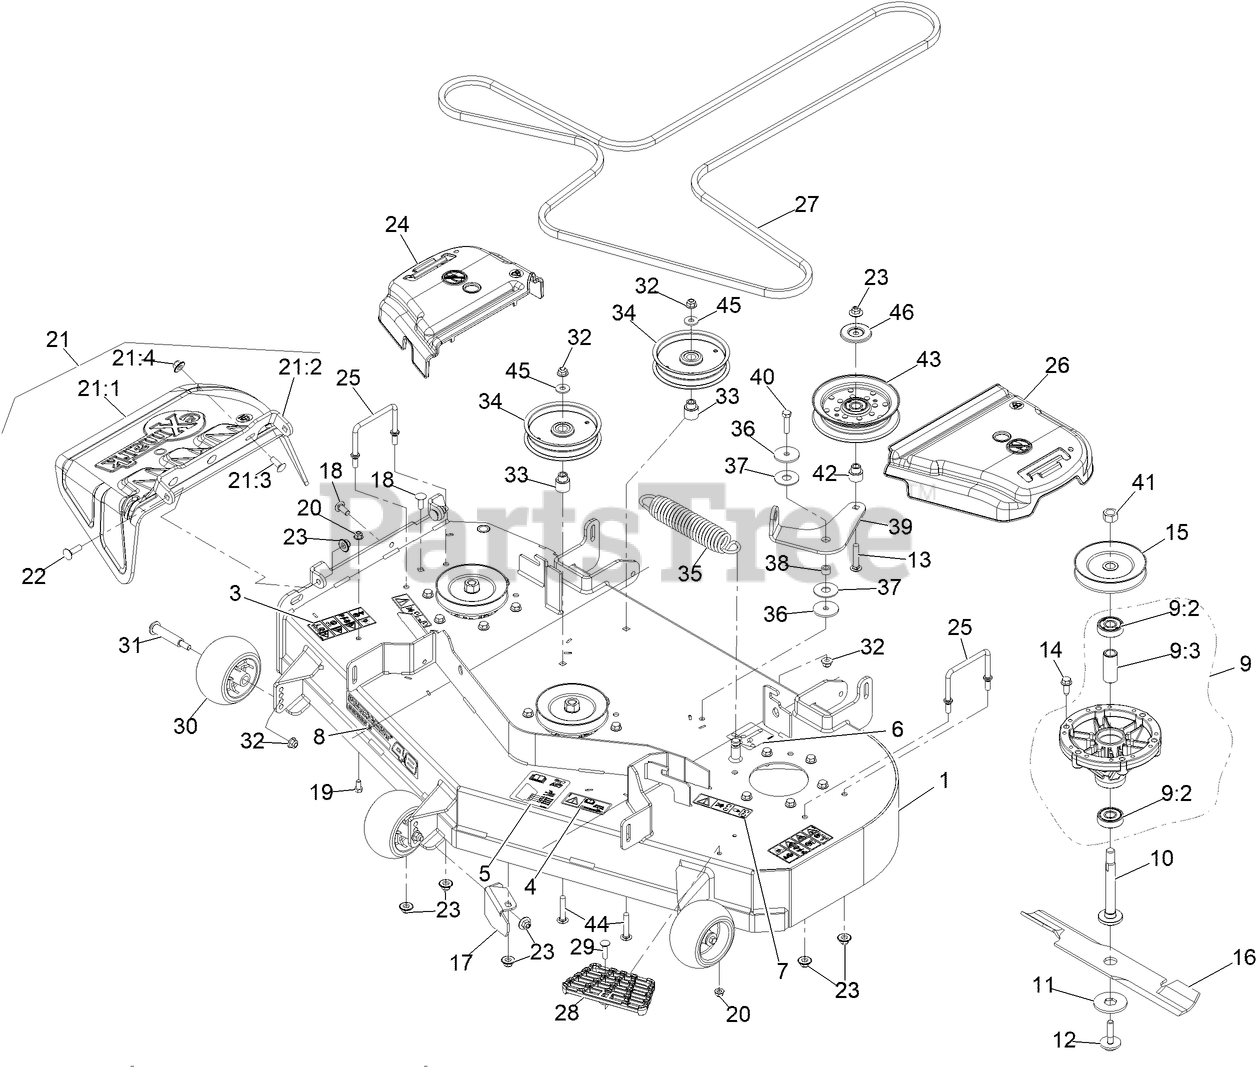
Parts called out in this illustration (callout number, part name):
1	ASM-Deck W/Decals 483
3	DECAL-DANGER, DECK
4	DECAL-TORQUE, BOLT
5	DECAL-ROLLER, ANTI-SCALP
6	DECAL-BELT ROUTING
7	DECAL-COVER, MISSING
8	DECAL-ULTRACUT 48 SERIES 3
9	ASM-CUTTER HOUSING
9:2	BEARING
9:3	SPACER-BEARING
10	SPINDLE-HEX PILOT
11	WASHER-HEX BLADE DRIVE
12	BOLT-BLADE, SEM
13	NUT-HEX
14	SCREW-FORMING, THREAD
15	Sheave-Blade Drive 4.77
17	BAFFLE,DISCHARGE 483
18	SCREW-CARR
19	SCREW-HH
20	NUT-HF, NI
21	ASM,DISCHARGE CHUTE
21:1	CHUTE,DISCHARGE
21:2	BRACKET,DISCHARGE CHUTE
21:3	SCREW-CARR
21:4	Nut-Nyloc 3/8-16 Flg
22	BOLT-CARR
23	Nut-Nyloc 3/8-16 Flg
24	COVER-BELT, RH
25	WIREFORM-COVER
26	COVER-BELT, LH
28	STEP-DECK
29	Bolt-Carriage 5/16-18 X 1 1/4
30	ROLLER-SCALP, ANTI
31	BOLT-SHOULDER
32	NUT-HF, NI
33	BUSHING-IDLER
34	PULLEY-IDLER
35	SPRING-EXTENSION
36	WASHER-REBOUND
39	Arm-Idler
40	SCREW-HH
41	SCREW-CARR
42	BUSHING-IDLER
43	IDLER-PULLEY, FLAT
44	BOLT-CARRIAGE
45	WASHER-HARDENED
46	SHIELD-DUST
